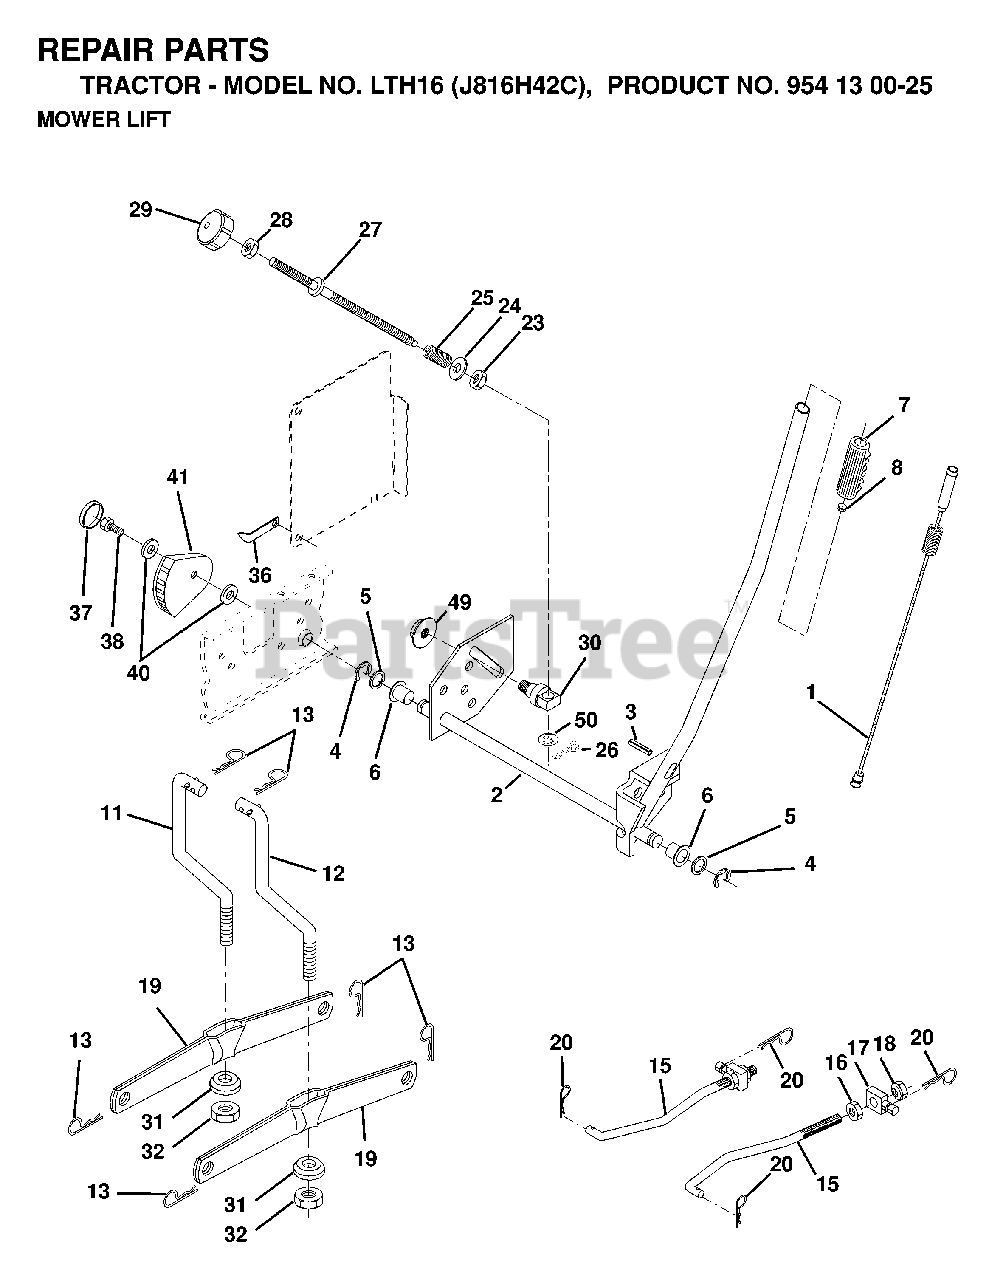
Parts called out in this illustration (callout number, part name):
1	WIRE ASM INNER W/ PLUNGER LT
2	SHAFT ASM R HANDLE
3	PIN GROOVE
4	RETAINING RING LT
6	BEARING.NYLON
7	GRIP HANDLE
8	PLUNGER BUT KIT
11	LINK LIFT LH
12	LINK LIFT RH
13	RETAINER-SPRNG RB
15	FRONT LINK
16	NUT
17	TRUNION
18	NUT
19	ARM.REAR.SUSPENSION
20	SPRING RETAINER
25	SPRING**
26	COTTER PIN
27	ROD ADJ LIFT
28	NUT
29	KNOB INF 3/8-16
31	BEARING PIVOT
32	NUT CROWNLOCK 3/8-24
36	POINTER, HEIGHT INDICATOR
37	PLUG,HOLE
38	SCREW
41	IND. HEIGHT STLT
49	NUT
50	NUT PUSH M
